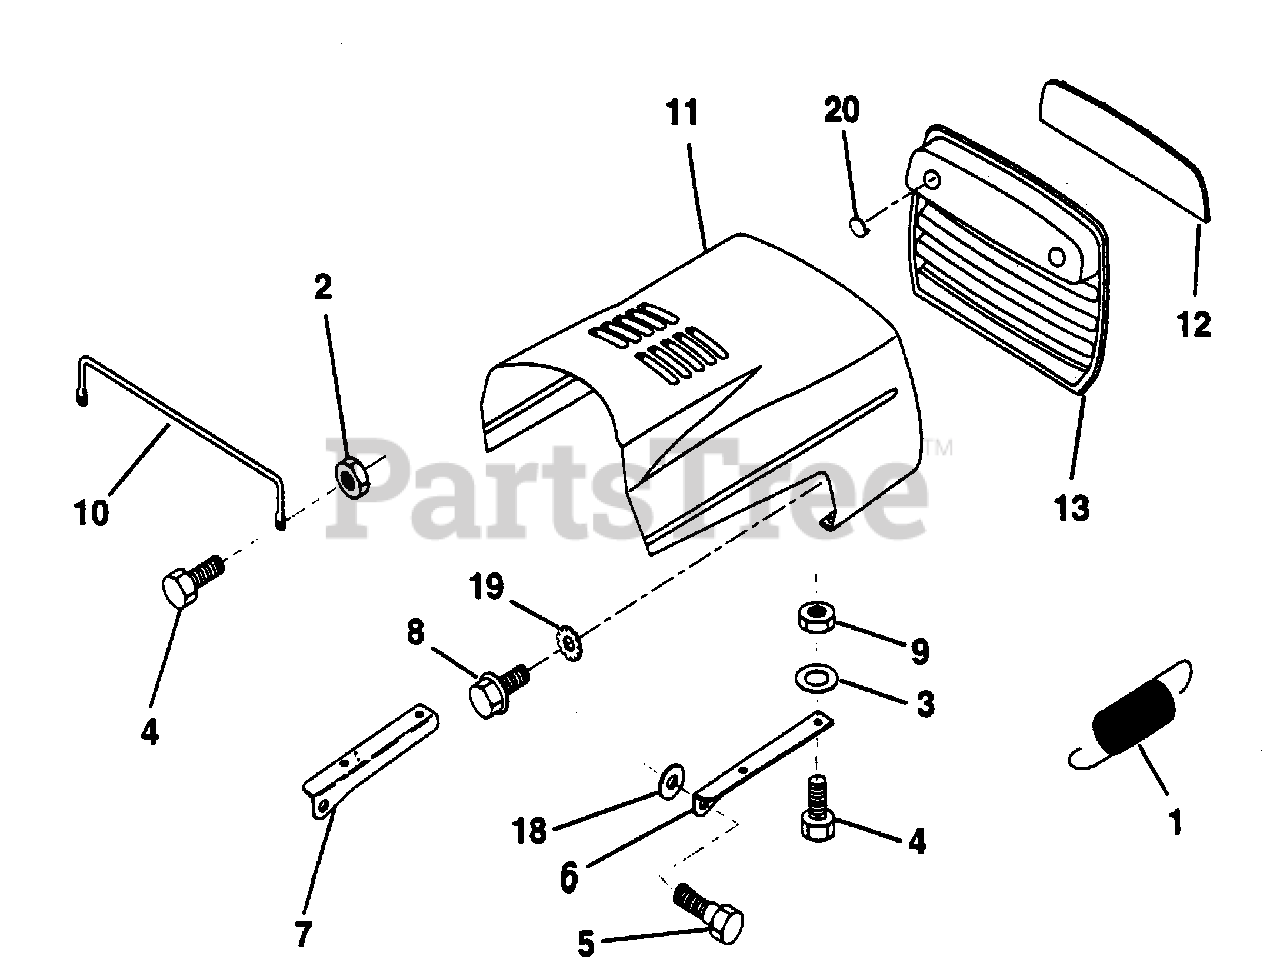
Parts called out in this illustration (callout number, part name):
1	Extension, Spring (AYP part number)
2	Nut, Hex, Keps 1/4-20 (AYP part number)
3	Washer, 9/32 x 7/8 x 16 Ga. (AYP part number)
4	Bolt, Hex Fin 1/4-20 x 3/4 Gr. 5 (AYP part number)
5	Bolt, Shoulder (AYP part number)
6	Bracket, Hood R. H. (AYP part number)
7	Bracket, Hood L.H. (AYP part number)
8	Screw Sltd. Hex Hd W/PL Washer (AYP part number)
9	Nut Lock W/Insert 1/4-20 UNC (AYP part number)
10	Brace, Hood (AYP part number)
11	Hood (AYP part number)
12	Lens Clear Bar (AYP part number)
13	Grille (AYP part number)
18	Washer 11/32 x 11/16 x 16 Ga. (AYP part number)
19	Washer Lock 1/4 Int/Ext Tooth (AYP part number)
20	Plug, Socket Light
